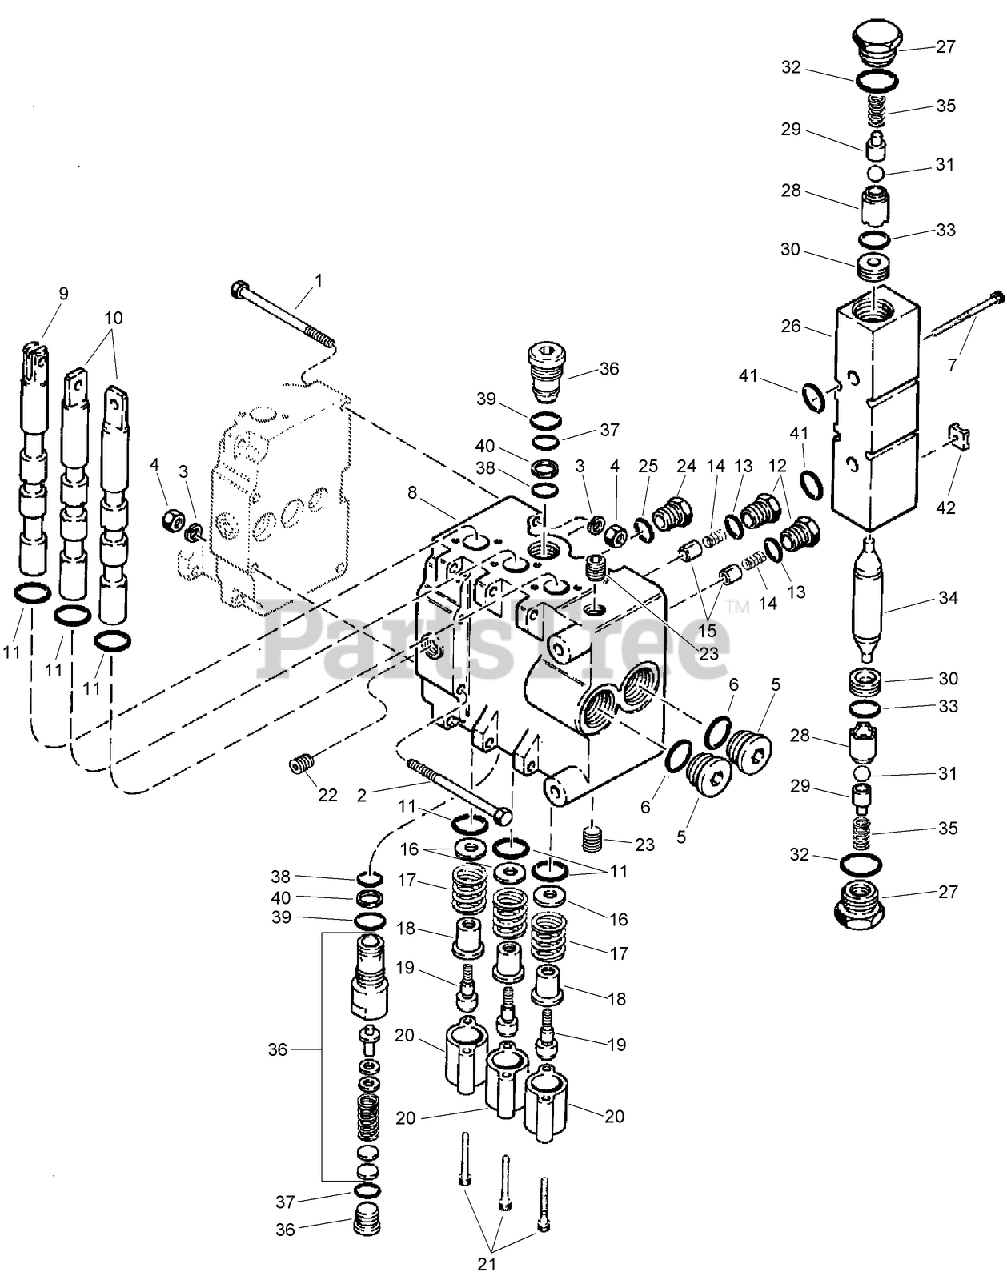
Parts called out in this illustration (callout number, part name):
1	SCREW-CAP
2	SCREW-HH
3	WASHER-FLAT
5	PLUG-SOCKET HEAD
6	O-RING
8	BODY-outlet section
9	SPOOL-stabilizer
10	SPOOL-dual control
12	PLUG ASM
14	SPRING-poppet
15	Poppet-Load Check
16	WASHER-FLAT
17	SPRING-RETURN
18	SPACER-spring
19	BOLT-shoulder, special
22	PLUG-seal
23	PLUG
24	PLUG ASM
26	BODY-pilot check
27	PLUG-pilot check
28	SLEEVE-pilot check
29	RETAINER-ball
30	SEAT-pilot check
31	BALL-pilot check
32	O-RING
33	O-RING-5/8 ID x 1/16 inch wide
34	PLUNGER-pilot check
35	SPRING-pilot check
36	Valve-Relief
39	O-RING
40	RING-BACKUP
42	ORIFICE
